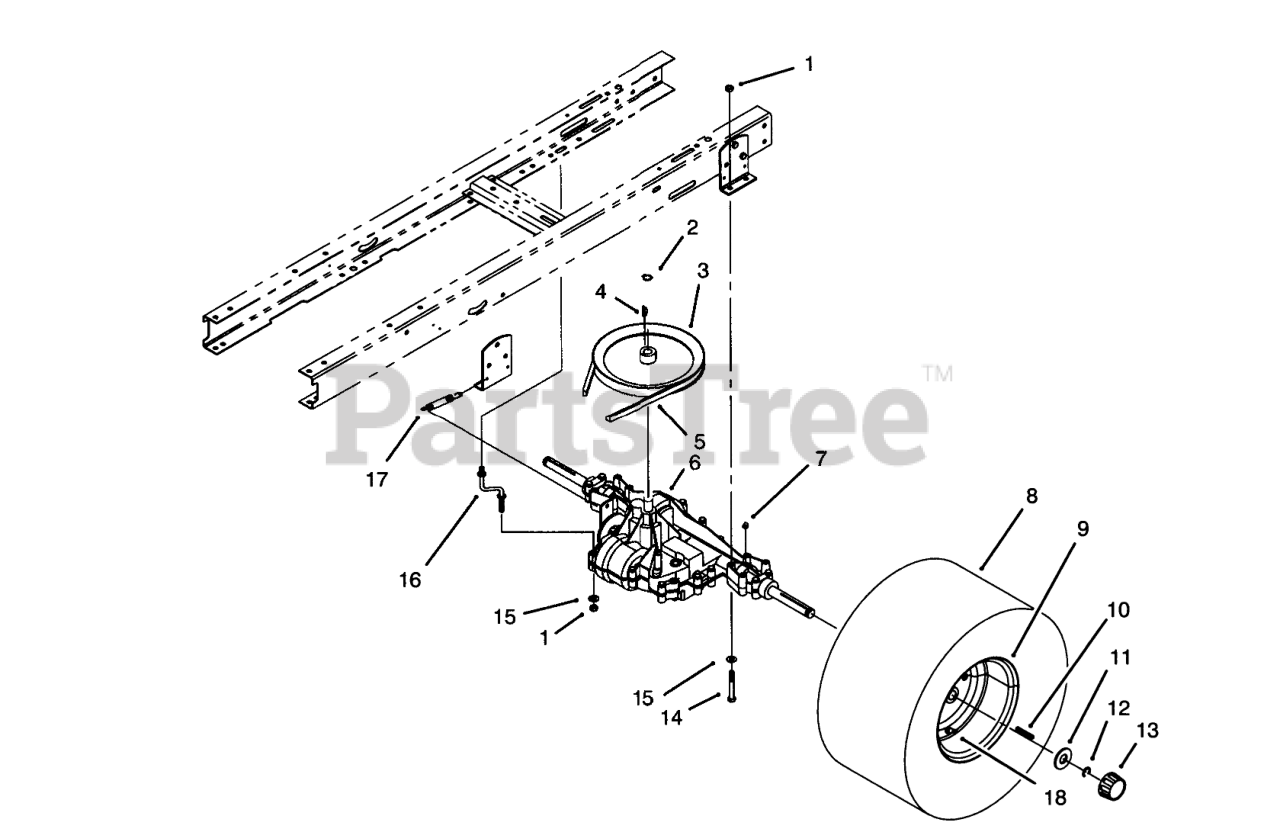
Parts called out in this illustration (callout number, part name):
1	NUT-LOCK, NI
2	RING-SNAP, EXTERNAL
3	PULLEY-TRANSMISSION
4	KEY-WOODRUFF
5	V-BELT
6	Transaxle
7	FITTING-LUBE, 45 DEG
8	TIRE 18 X 9.50 X 8
10	KEY-SQUARE
11	WASHER-PLAIN
12	E-RING
13	CAP-HUB
14	SCREW-HH
15	WASHER-PLAIN
16	TORQUE STRAP
17	SPRING-RETURN, BRAKE
18	STEM-VALVE
